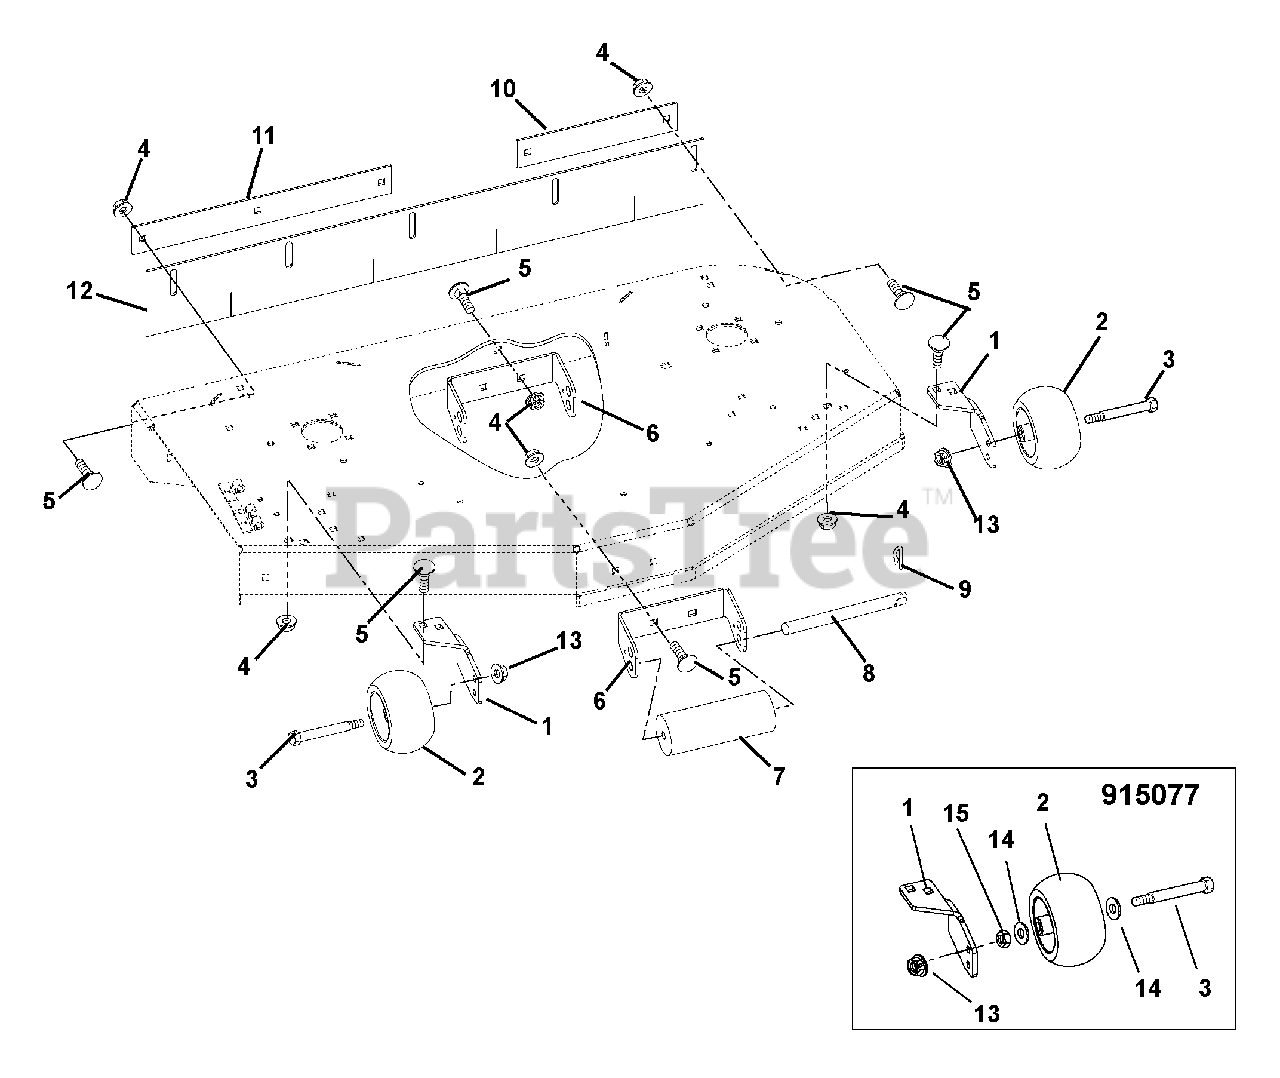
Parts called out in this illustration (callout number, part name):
1	BRACKET, ANTI SCALP
2	WHEEL 5 X 3
2	ROLLER
3	BLT-SHLDR .38-16X2.50 HWH G5
3	@BLT-HEX .38-16X3.50 GR5 YWZC
4	@NUT-LK-NYL-FLG .38-16 YWZC
5	@BLT-RDHDSQNK .38-16X1.00 G5YZ
6	BRACKET, ROLLER MOUNT
7	ROLLER
8	PIN, ROLLER
9	PIN, SPRING CLIP
10	BAR, LH RETAINER STRIPER
11	BAR, RETAINING STRIPER-44"
11	BAR, RETAINING STRIPER-52"
11	BAR, RETAINING STRIPER-40"
12	STRIPER, RUBBER-44"
12	STRIPER, RUBBER-48"
12	STRIPER, RUBBER-52"
12	STRIPER, RUBBER-40"
13	@NUT-LK-TOP-FLG .38-16 YWZC
14	@WSHR-FL-STL.406X.812X.065 YWZ
15	@NUT-LK-CTR-JAM .375-16 YWZC
